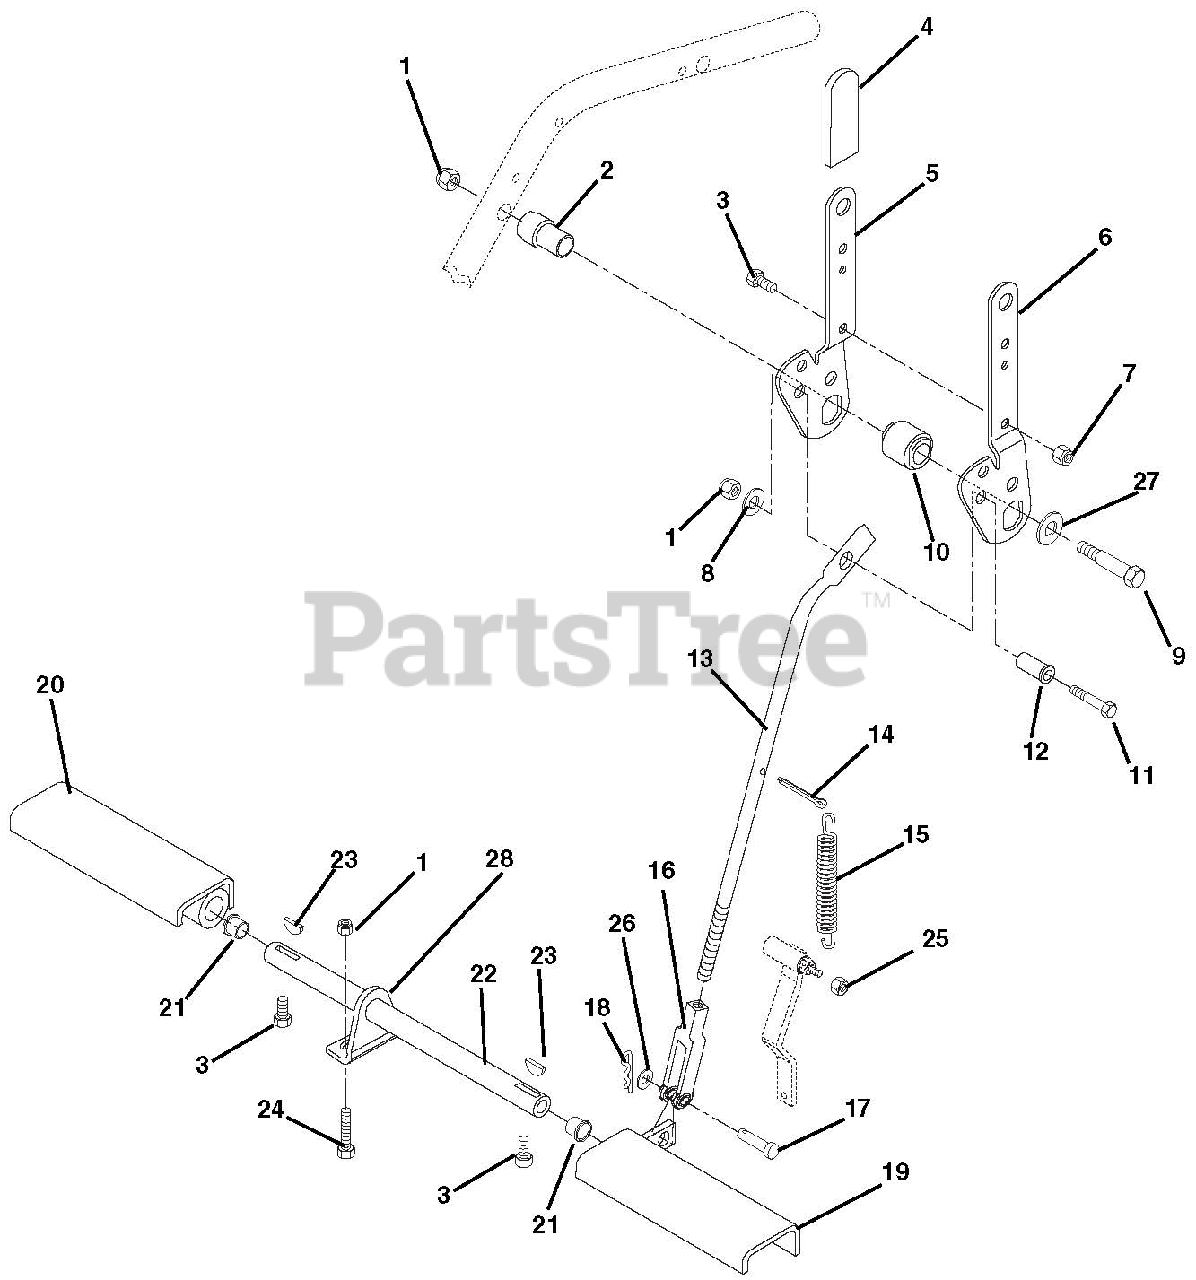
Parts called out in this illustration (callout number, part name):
1	@NUT-LK-NYL .38-16 YWZC
2	PVT,HAND LVR L.H.
3	@BLT-HEX .25-20X.50 GR5 YWZC
4	GRIP,HANDLE
5	HNDL,CONTROL L.H.
6	HNDL,CONTROL R.H.
7	@NUT-LK-NYL .250-20 YWZC
8	@WSHR-FL-STL.281X.62X.065 YWZC
9	BLT-HEX .38-16X3.75 PL
10	BUSH.,F.751X1.13X1.07 NY
11	@BLT-HEX .38-16X1.50 GR5 YWZC
12	BSHG-FLG .257X.38X1.080 NYL
13	ROD, BRAKE PULL
14	@PIN-CTR .09X1.00 EXTPRSQCT YZ
15	SG-TENS .063X.62X2.75
16	CLEVIS, .38-24 ADJ.
17	PIN-CLEV .38X1.25 YWZC
18	PIN-HAIR INT .08X.18X1.18 YWZC
19	WMT, BRAKE ARM
20	WMT, BRAKE ARM
21	BSHG-FLG .630X1.000X.625 NY
22	SHFT,SPEED CTL CAM
23	KEY-WDRF .125X.75
24	@BLT-HEX .38-16X1.00 GR5 YWZC
25	@NUT-LK-CTR .38-16 YWZC
26	@WSHR-FL-STL.406X.812X.065 YWZ
27	@WSHR-FL-STL.531X1.06X.095YWZC
28	BRACE, BRAKE
